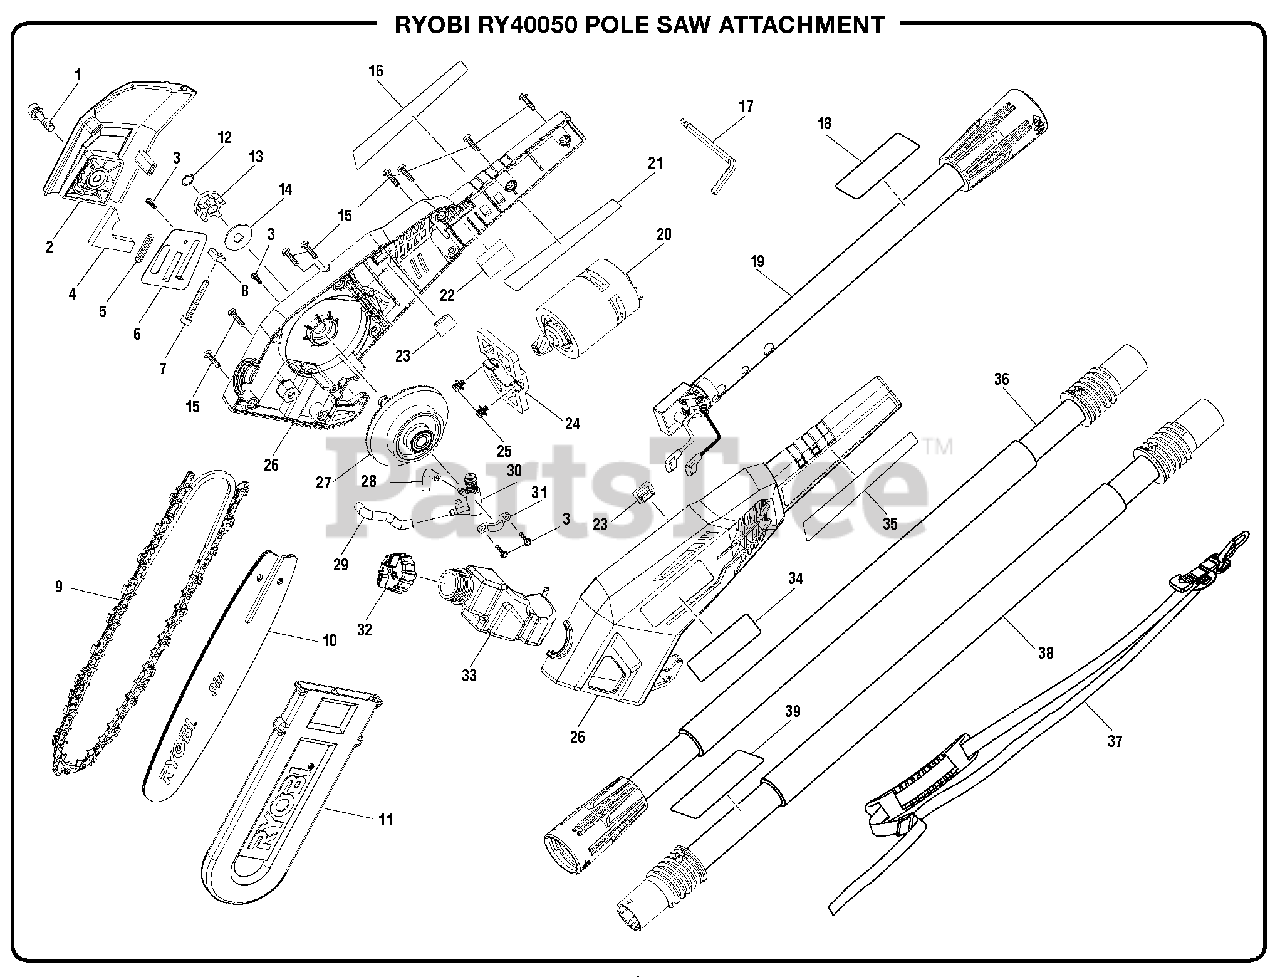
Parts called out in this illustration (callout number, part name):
1	Screw (M6 x 25 mm)
2	Chain Cover Assembly
3	Screw (M3 x 10 mm)
4	Press Block (Seal)
5	Rubber Seal
6	Guide Bar Plate
7	Screw (M5 x 37 mm, Soc. Hd.)
8	Adjustment Block
10	Guide Bar
12	Retaining Ring
14	"D" Washer (OD24 x ID 10 x 1.2t)
15	Screw (M4 x 18 mm, T20 Torx Pan Hd.)
16	Connexion Logo Label (Left)
17	Hex Key (5 mm)
18	Icon Warning Label
19	Upper Pole Assembly
20	Motor Assembly
21	Data Label
22	Rubber Fix Block
23	Rubber Plate
24	Mounting Plate
25	Screw w/Washer (M5 x 9 mm, Pan Hd.)
26	Motor Housing Assembly
27	Gear Assembly
28	Inlet Tube
29	Outlet Tube
30	Oil Pump Assembly
32	Oil Tank Cap Assembly
33	Oil Tank Assemlby
34	Logo Label
35	Connexion Logo Label (Right)
36	Extended Boom Assembly
37	Shoulder Strap Assembly
38	Boom Assembly
39	Warning Label (Fr/Sp)
